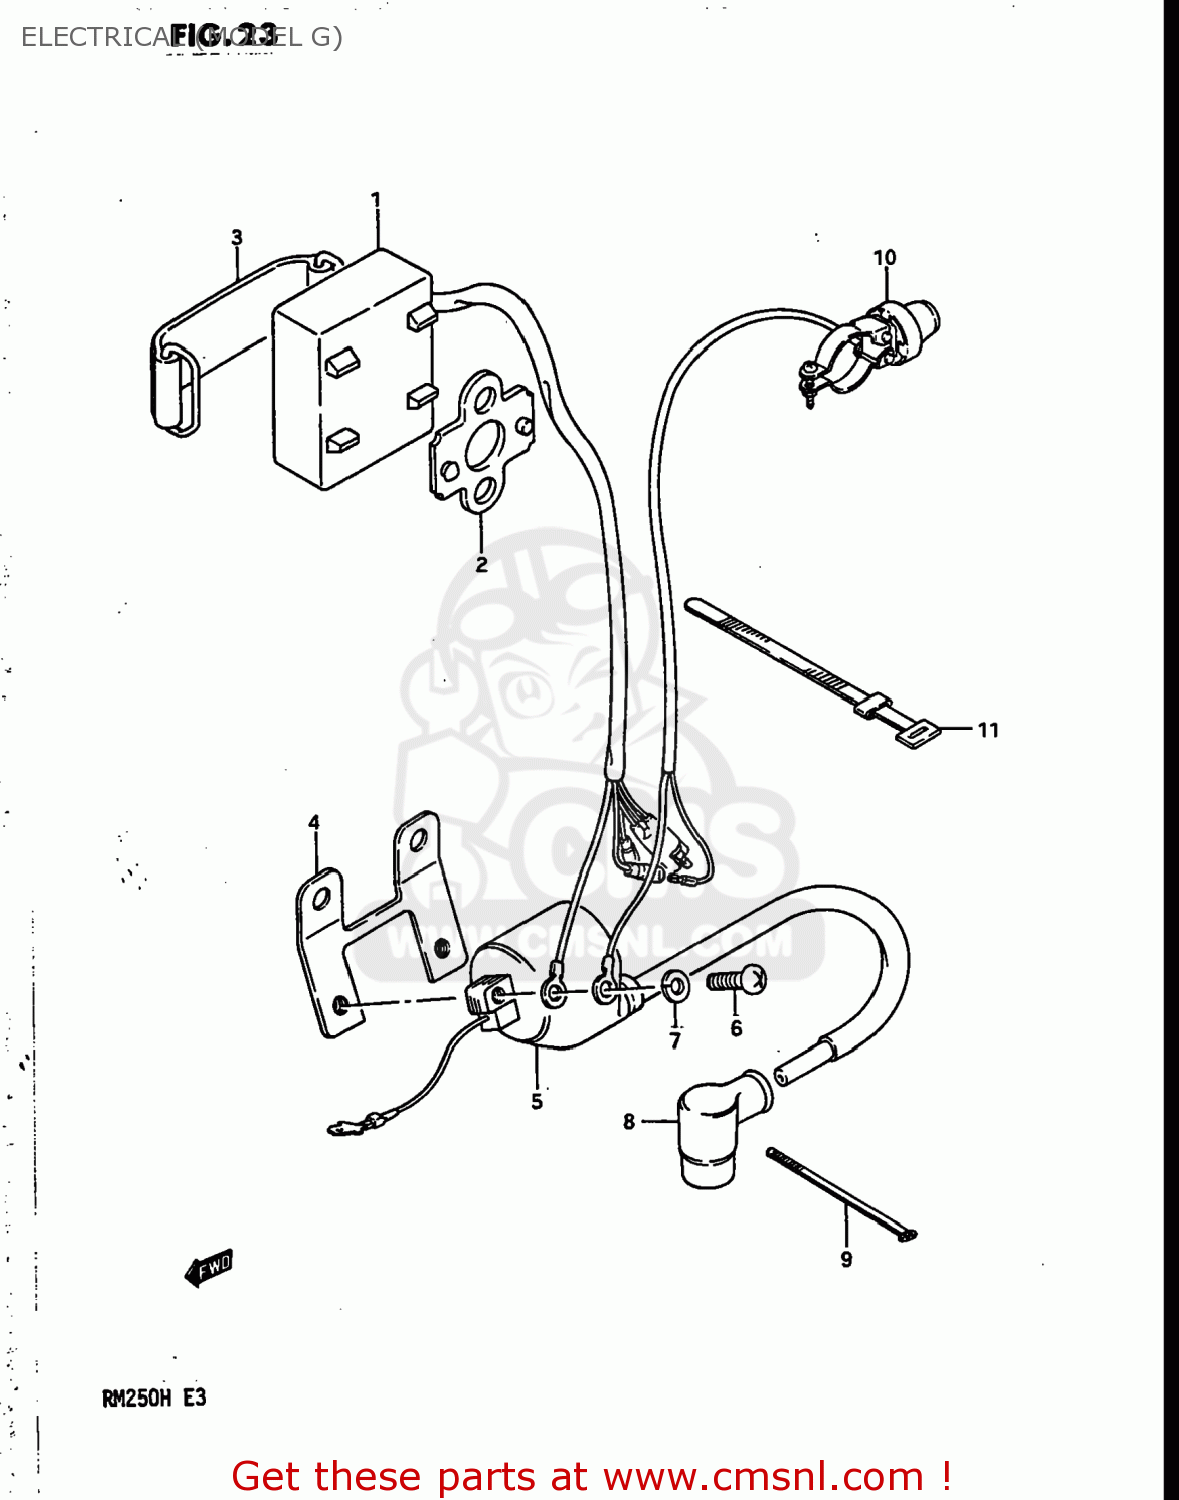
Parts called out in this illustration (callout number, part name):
1	UNIT ASSY,CDI
2	PROTECTOR,CDI UNIT
3	BAND
4	BRACKET,IGNITION COIL
5	COIL ASSEMBLY,IGNITION
6	SCREW
7	WASHER,LOCK
8	CAP,SPARK PLUG
9	CLAMP
10	SWITCH ASSEMBLY
11	CLAMP(L:120)
